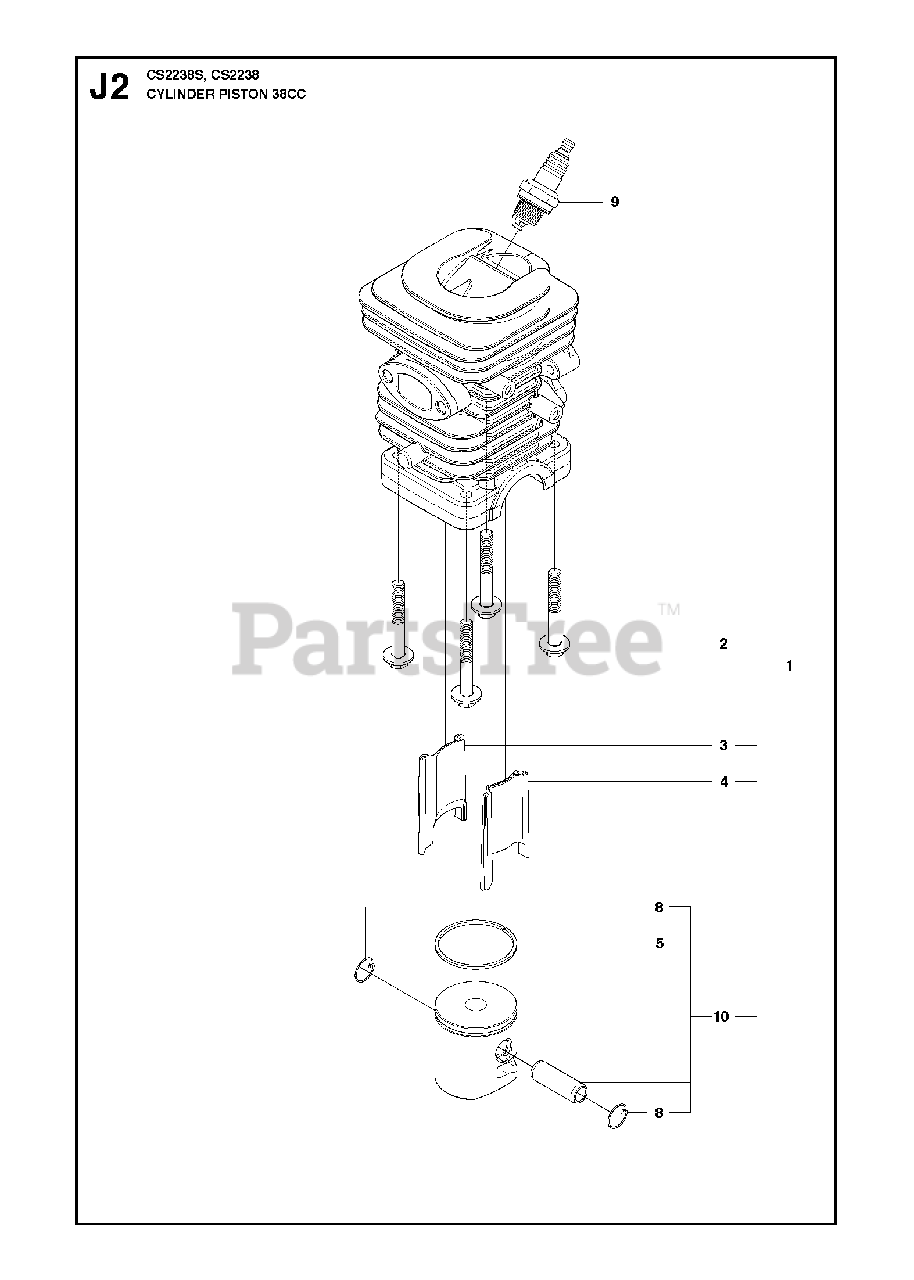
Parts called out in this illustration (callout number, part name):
1	%KIT, CYLINDER & PISTON
2	BOLT
3	CYLINDER INSERT RIGHT 38CC
4	CYLINDER INSERT LEFT 38CC
5	PISTON RING
8	C-CLIP,PSTN PIN 36/41
9	SPARK PLUG RCJ7Y
10	PISTON KIT
